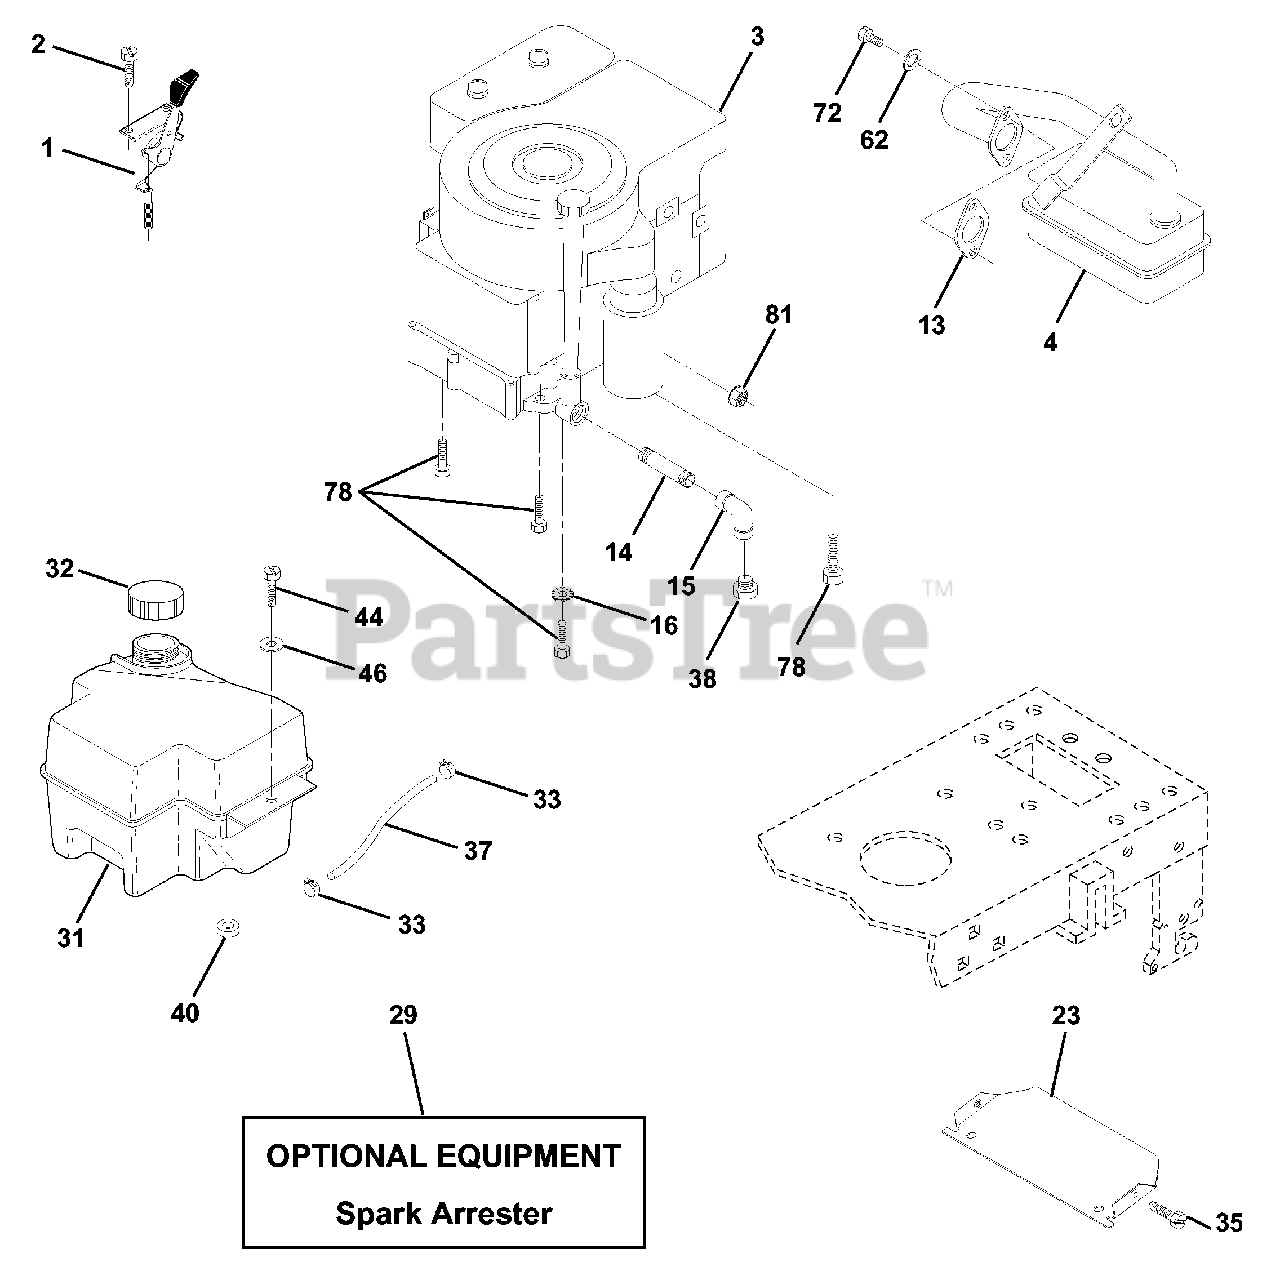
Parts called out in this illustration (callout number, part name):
1	Control Th/ch 23 5 LH Flag
2	Screw Hex Thd Cut 1/4-20x5/8 T
4	Muffler LT B&S 12/12.5/13HP
13	Gasket Eng 1 313 Id Tin Plated
14	Nipple Pipe 3/8 Npt X 3"
15	Elbow Std 90 Degree 3/8-18 Npt
16	Washer Lock Ext Tooth 3/8
23	Shield Heat
29	Kit Spark Arrestor (Flat Scrn)
31	Tank Fuel Front 2 00
32	Cap Asm Fuel W/sym Vented
33	Clamp Hose Black
35	Screw
37	Line Fuel 20"
38	Plug Oil Drain
40	Bushing Snap Nyl Blk Fuel Line
44	Screw Hexwsh Thdrol 1/4-20x3/4
46	Washer 9/32 X 7/8 X 16 Ga
62	Washer Lock Hvy Hlcl Spr 5/16
72	Screw Hexhd Cap 5/16-18x 3/4
78	Screw Thdrol 3/8-16x1-1/4 TYTT
81	Nut Flange 1/4-20 Starter Nut
